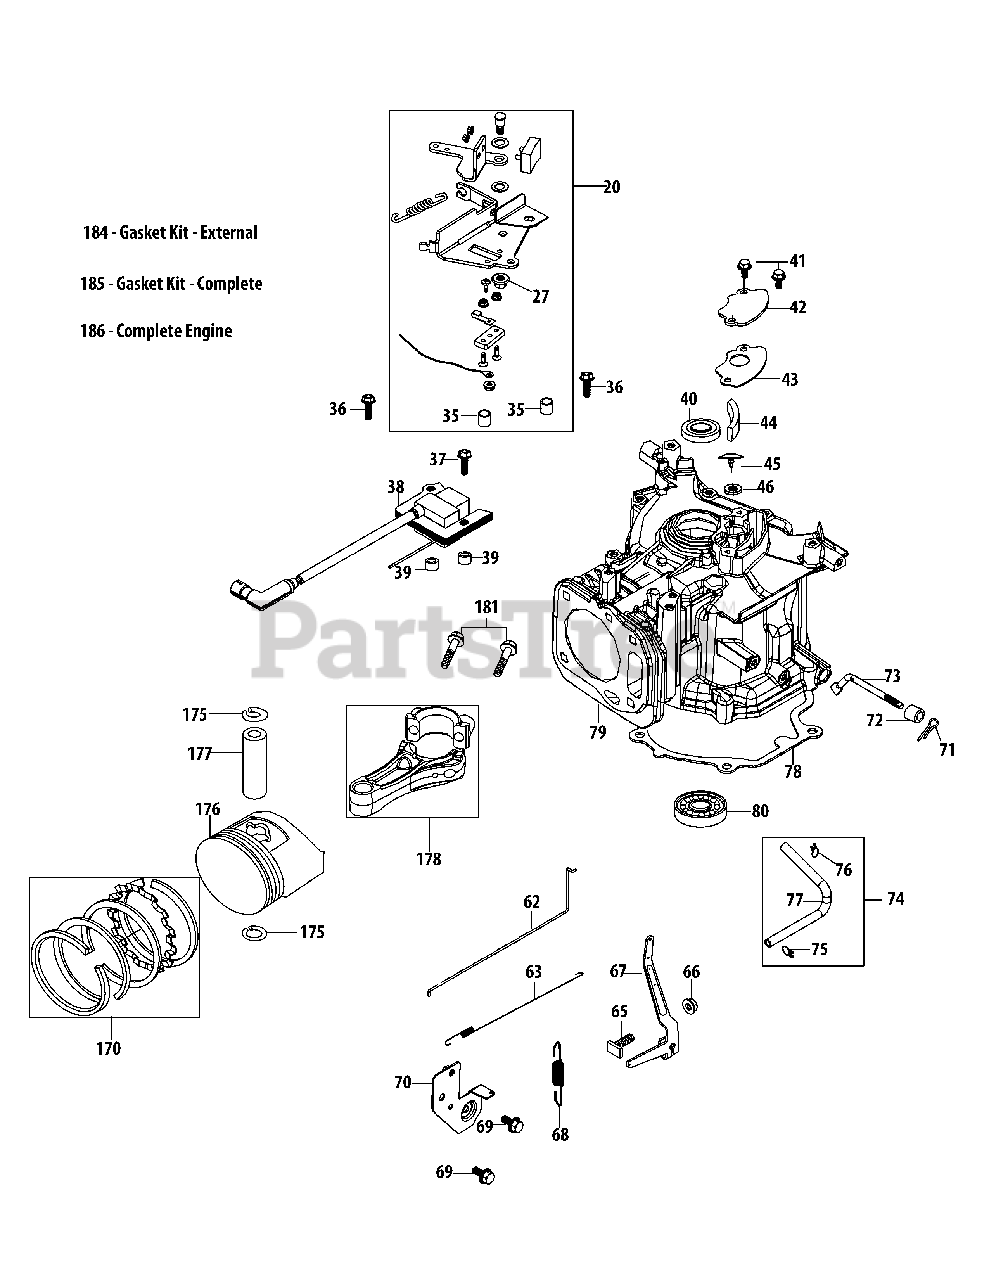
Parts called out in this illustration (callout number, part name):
20	Brake Assembly
27	Brake Arm Nut
35	Brake Spacer
36	Bolt M6X35
37	Bolt M6X30
38	Ignition Coil Assembly
39	Ignition Coil Spacer
40	Upper Crankshaft Seal
41	Bolt M6X14
42	Breather Cover Plate
43	Breather Gasket
44	Breather Screen
45	Breather Valve Base
46	Breather Valve
62	Throttle Linkage
63	Throttle Linkage Spring
65	Governor Arm Bolt
66	Governor Arm Nut M6
67	Governor Arm
68	Governor Spring
69	Bolt M6X12
70	Component Bracket
71	Governor Arm Shaft Cotter Pin
72	Governor Seal
73	Governor Arm Shaft
74	Breather Hose Assembly
75	Breather Hose Clamp
76	Breather Hose Clamp
77	Breather Hose
78	Crankcase Cover Gasket
79	Short Block Assembly
80	Main Bearing
170	Piston Ring Set
175	Piston Pin Snap Ring
176	Piston
177	Piston Pin
178	Connecting Rod Assembly
181	Connecting Rod Bolt
184	Gasket - External
185	Gasket Kit - Complete
186	Complete Engine
